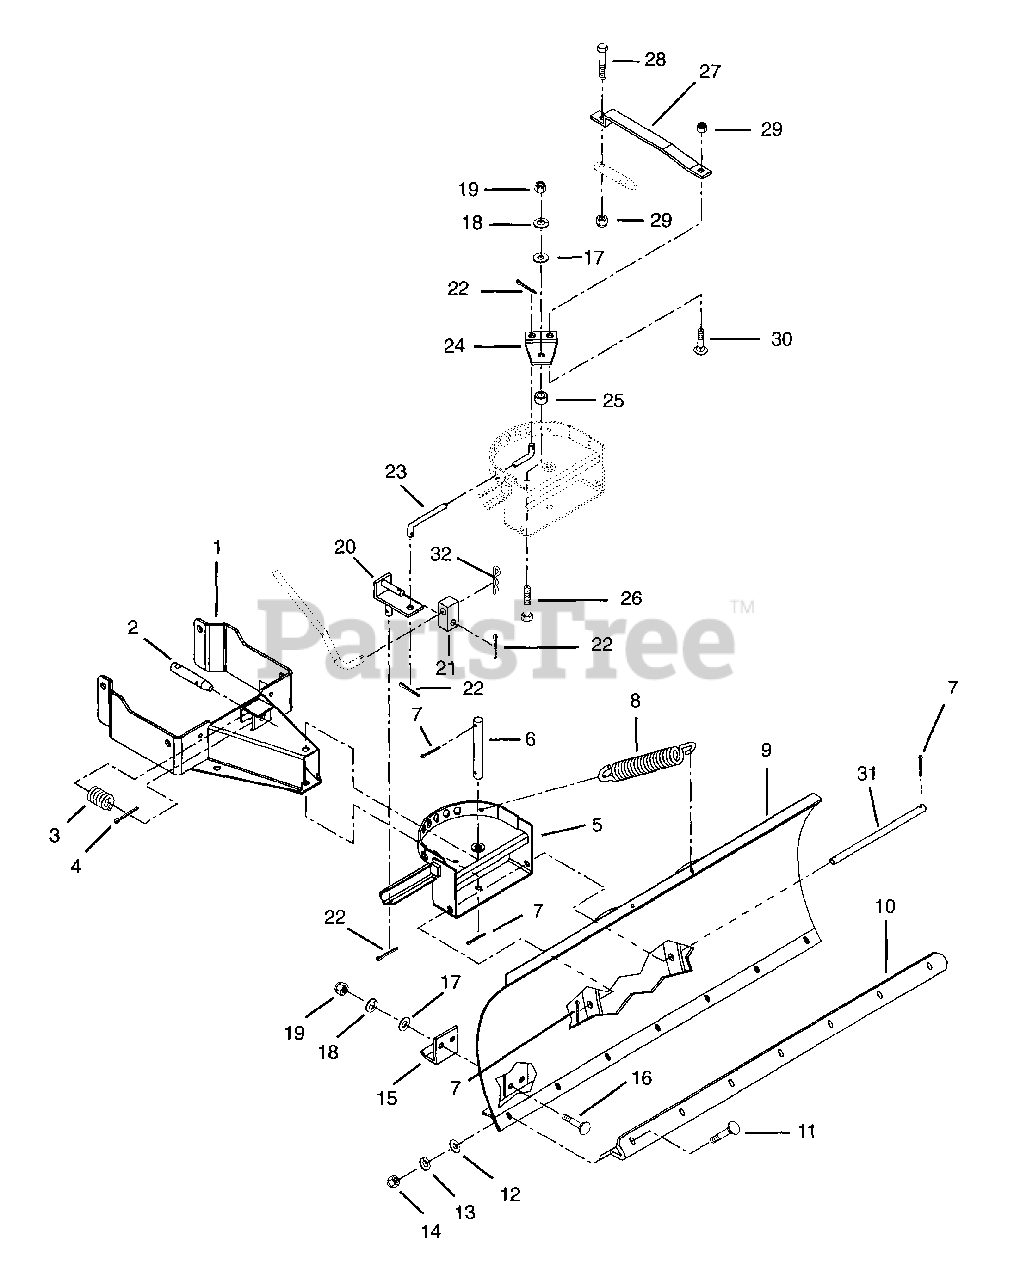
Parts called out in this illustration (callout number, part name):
1	FRAME - PUSH
2	LATCH PIN
3	SG-COMP .080X.85X1.44
4	@PIN-CTR .12X1.00 EXTPRSQCT YZ
5	SUPPORT
7	@PIN-CTR .18X1.00 EXTPRSQCT YZ
8	SG-TENS .187X1.50X9.94 WLD 40
9	WELDMENT, SNOW BLADE
10	WEAR PLATE
11	@BLT-RDHDSQNK .31-18X1.00 G5YZ
12	@WSHR-FL-STL.38X.875X.083 YWZC
13	@WSHR-LK .31X.078 REG YWZC
14	@BLT-RDHDSQNK .31-18X1.00 G5YZ
15	SKID SHOE
16	@BLT-RDHDSQNK .38-16X1.00 G2YZ
17	@WSHR-FL-STL.438X1.00X.083 YWZ
18	@WSHR-LK .38X.094 REG YWZC
19	@NUT-HEX .38-16 YWZC
21	UNIVERSAL BLOCK JOINT
22	@PIN-CTR .12X.75 EXTPRSQCT YWZ
24	PIVOT PLATE
25	SPACER .406X.749X.162
26	@BLT-HEX .38-16X1.00 GR5 YWZC
28	@BLT-HEX .31-18X1.25 GR5 YWZC
29	@NUT-LK-CTR .31-18 YWZC
30	BLT-RDHDSQSHK.31-18X.75 GR2 YW
32	PIN-HAIR INT .08X.18X1.18
